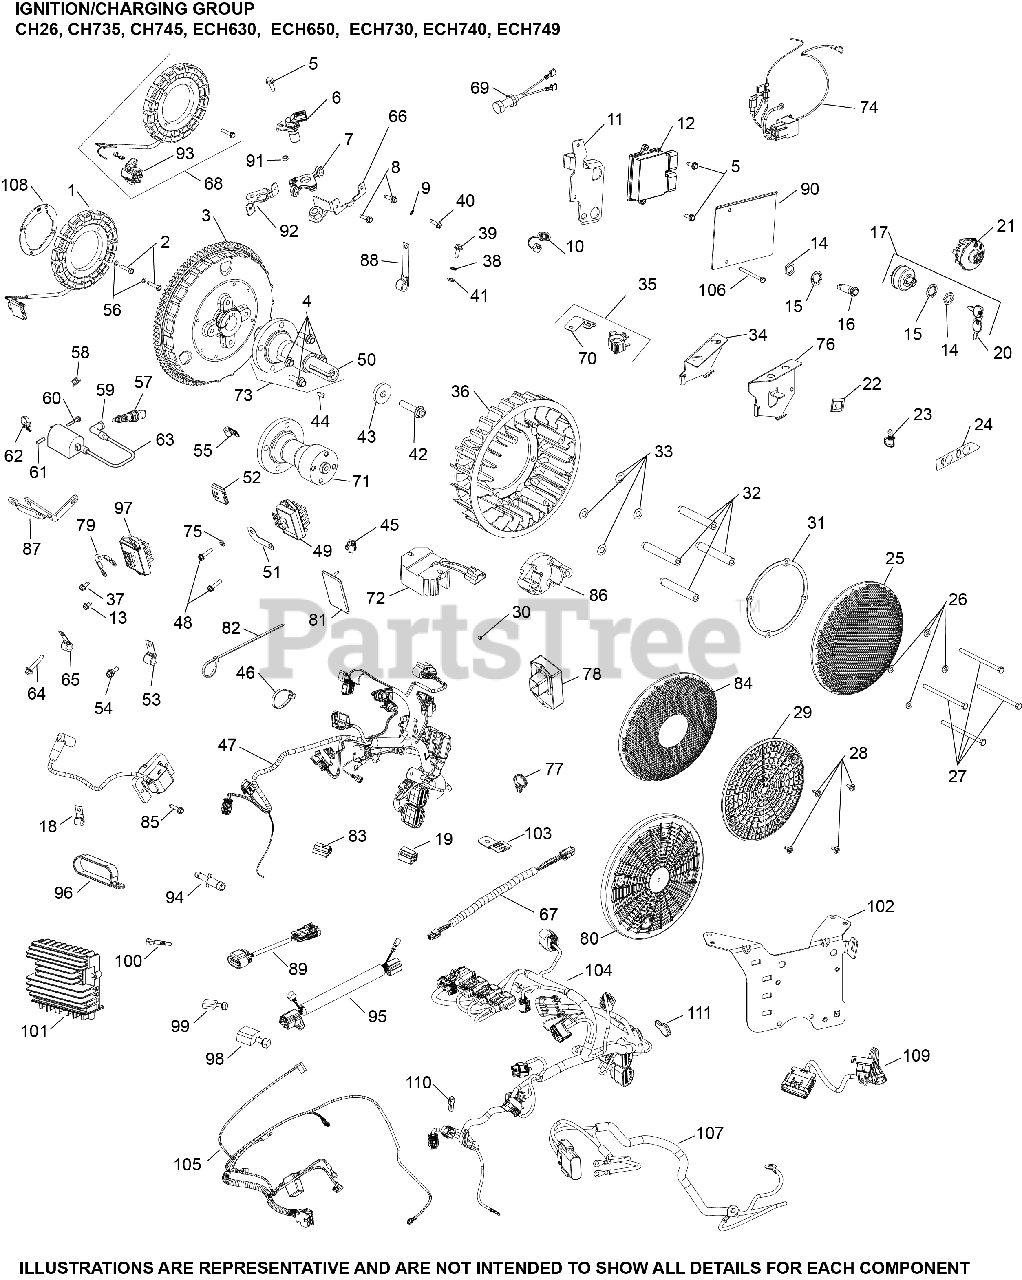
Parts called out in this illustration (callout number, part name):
1	KIT, 15 / 20 AMP STATOR
2	SCREW, THREAD FORMING
3	FLYWHEEL, ASSEMBLY
6	SENSOR, SPEED
8	SCREW, THREAD FORMING
9	WASHER, INT TOOTH LOCK #10
10	CAP, CONNECTOR
11	BRACKET, ECU
12	MODULE, ECU
20	KEY, SET OF 2
21	KIT, KEY SWITCH (SNAP-IN)
25	KIT, GRASS SCREEN
28	SCREW, FLG SEMS M4X.7X25
30	SCREW, FLG M10X1.5X45 - (#25086361S)
35	KIT, MOUNTING CLIP
36	FAN USE 24 755 253-S
37	SCREW, THREAD FORMING
38	WASHER, INT TOOTH LOCK 1/4"
41	WASHER, FLAT 1/4" (O.D. 1/2")
43	WASHER, FLAT 13/32"
44	KEY, 3/16" X 5/8"
47	HARNESS, WIRING ASSEMBLY
48	SCREW, HEX FLANGE HI-LO
52	CONNECTOR
54	BOLT, SHOULDER
57	SPARK PLUG, RFI
62	CLIP, SNAP-IN
63	COIL, IGNITION - EFI (RFI/EMC)
64	SCREW, FLG M6X1.0X34
70	CLIP, MOUNTING BRACKET USE 25 154 21-S
80	SCREEN, GRASS
92	BRACKET, SENSOR
97	REGULATOR, RECT (20-30AMP, FW W/OVP)
